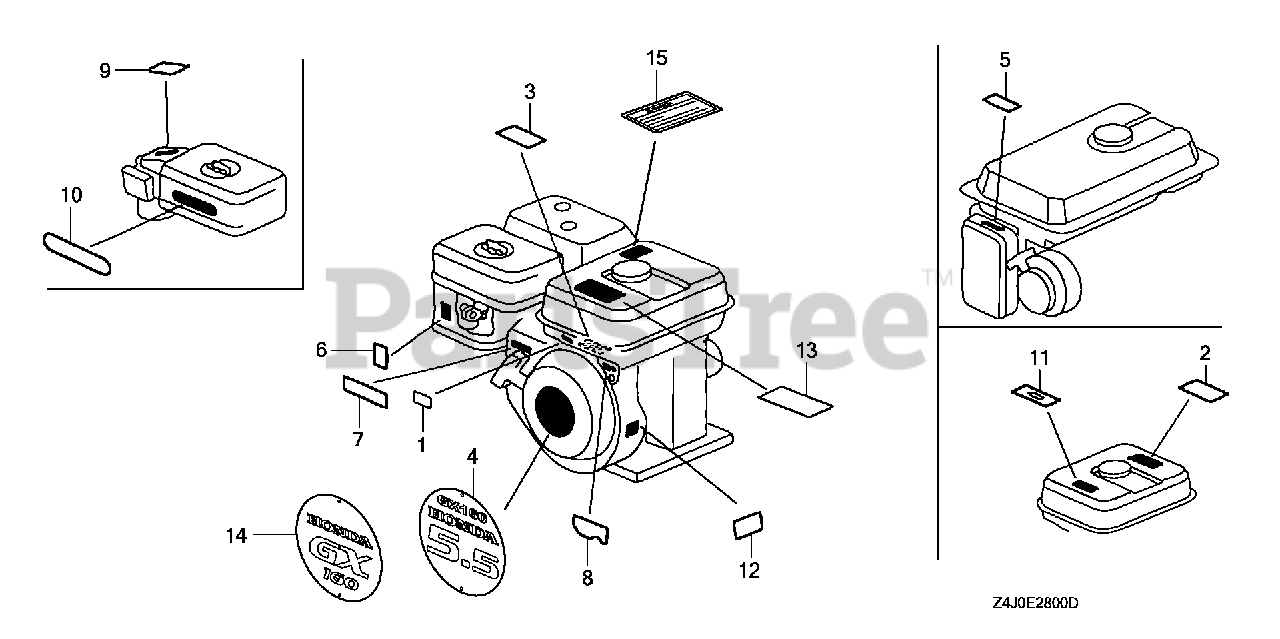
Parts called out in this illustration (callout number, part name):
4	EMBLEM (GX160)
6	MARK, CHOKE (GRAY)
13	MARK, OPERATOR CAUTION (ENGLISH)(MADE IN JAPAN)
13	MARK, OPERATOR CAUTION (PICTOGRAPH)(MADE IN JAPAN)
14	EMBLEM (GX160)
15	MARK, EX. CAUTION (ENGLISH)
